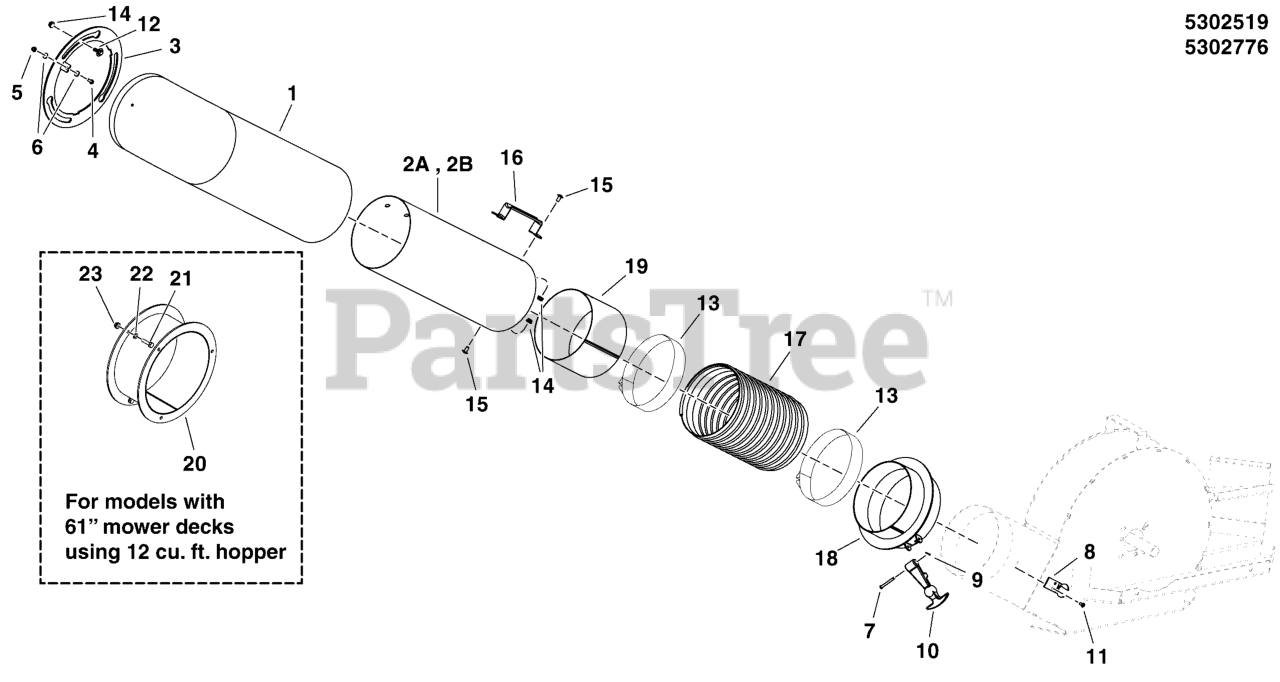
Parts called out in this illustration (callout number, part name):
1	ELBOW, ABS PLASTIC, HOPPER
3	WELD, FLANGE ASSY - BLK
4	SCREW, #10-24 X 3/4 ROUND PHILLIPS
5	NUT, #10-24 HEX NYLON LOCK
6	WASHER, #10 SAE
7	PIN, CLEVIS
8	LATCH, RUBBER, KEEPER
9	PIN, COTTER
10	LATCH, RUBBER
11	RIVET-POP.188 .429L AL,AL STEM.37HD DIA
12	SCREW, HEX WASHER H
13	CLAMP, HOSE, UPPER
14	NUT, 1/4-20 HEX NYLOCK FLANGE
15	SCREW, 1/4-20 X 1/2 ALLEN BH
16	HANDLE CONNECT TUBE
17	HOSE, FLEXIBLE, FAST-VAC
18	WELD, HOSE ATTACHMENT - BLK
19	WELD, THIMBLE, BAGGER - BLK
20	WELD, ELBOW EXTENSION, HOPPERS - BLK
21	BOLT, 1/4-20 X 1" GD5 CZ
22	WASHER, 1/4 SAE
23	NUT, 1/4-20 HEX NYLOCK FLANGE
